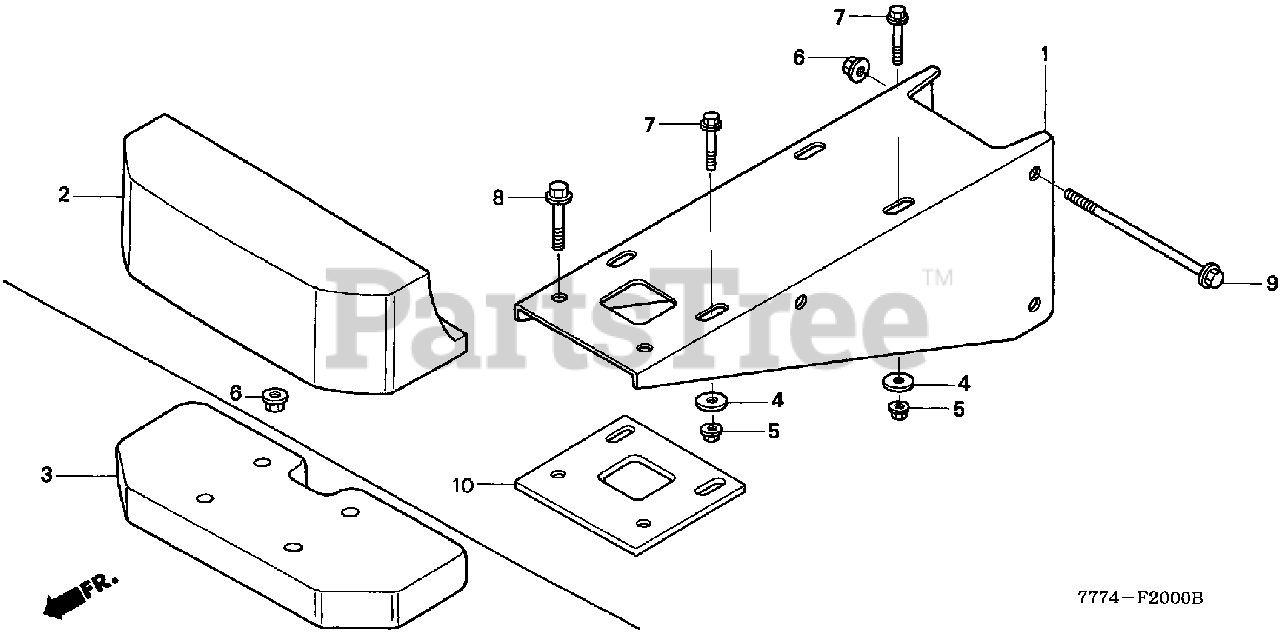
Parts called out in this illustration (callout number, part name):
1	BED, ENGINE
2	WEIGHT, FR.
3	WEIGHT, SUB
4	WASHER (8X22)
5	NUT, FLANGE (8MM)
6	NUT, FLANGE (10MM)
7	BOLT, FLANGE (8X35)
7	BOLT, FLANGE (8X40)
8	BOLT, FLANGE (10X70)
9	BOLT, FLANGE (10X130)
10	PLATE, ENGINE BED
